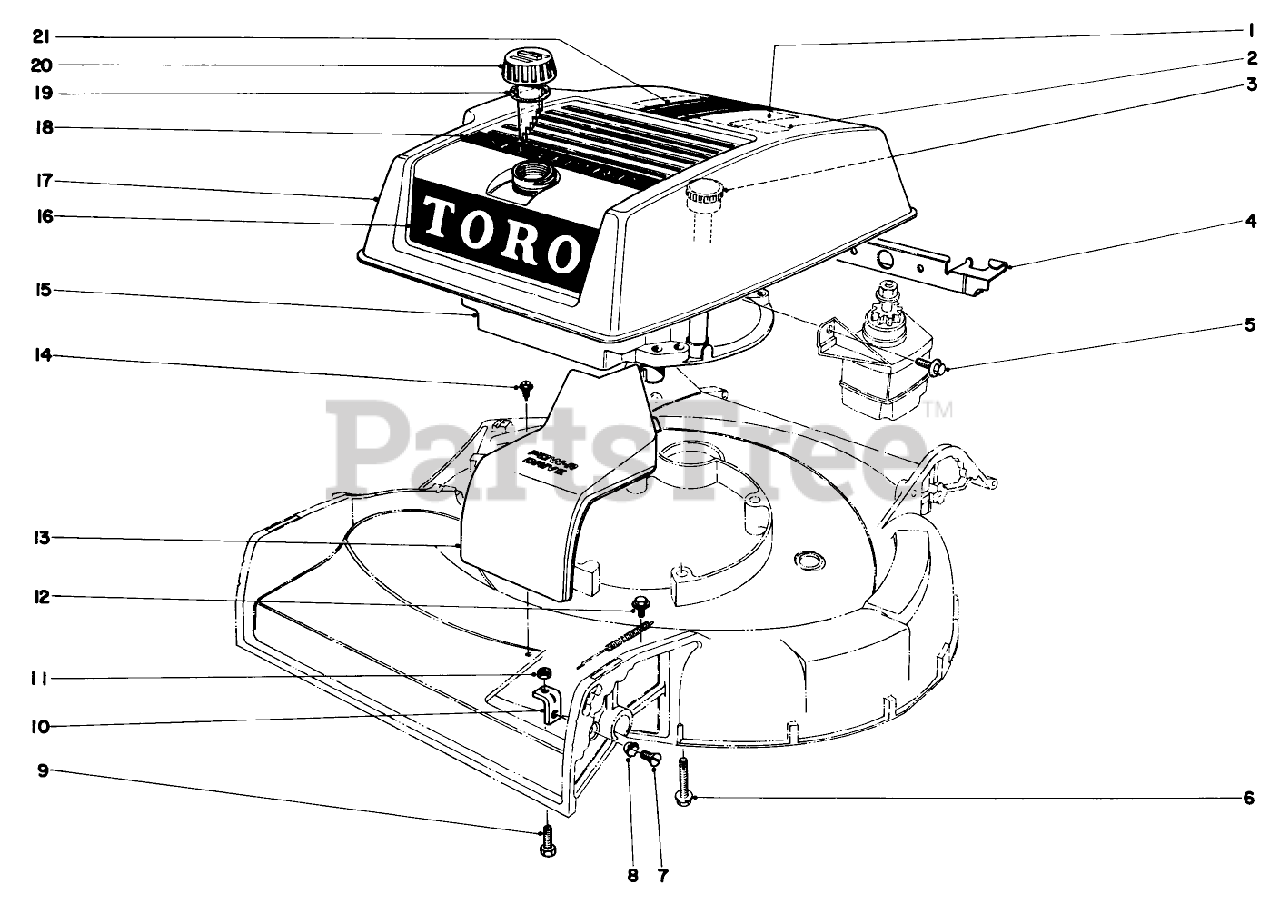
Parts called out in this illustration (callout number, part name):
1	Decal-Maintenance
2	Decal Caution
3	Dip Stick
4	Shroud Bracket
5	SCREW
6	3/8-16 X 2-3/4 CAPSCR
11	NUT-JAM
13	Belt Drive Cover
14	SCREW-HWHTF
15	Engine
16	Decal-Toro
17	Shroud
18	Decal-Key-Lectric
19	Gasket
21	Decal
